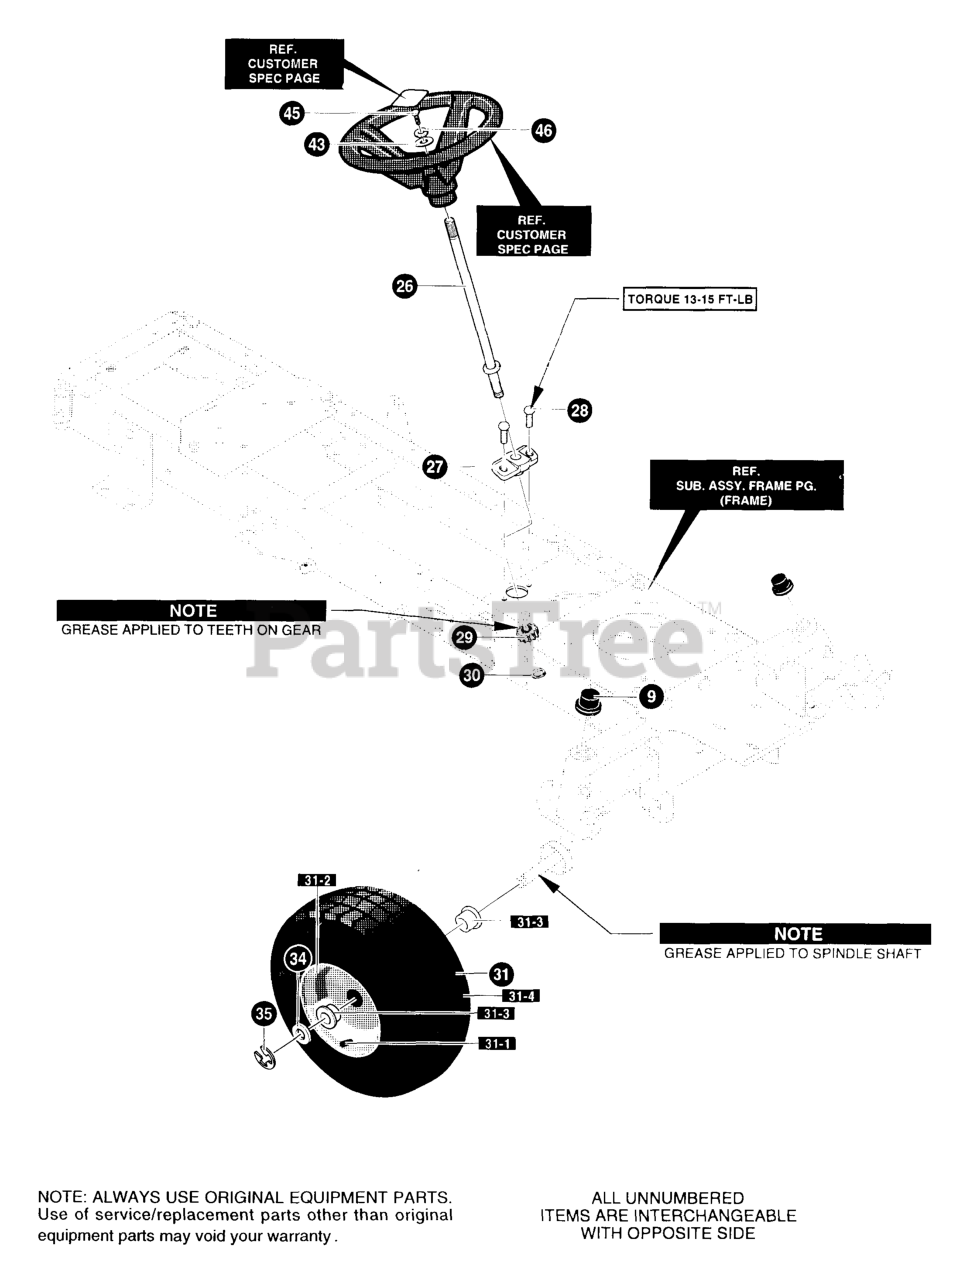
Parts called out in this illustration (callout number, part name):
26	SHAFT, STEERING
27	BEARING-LOWER
28	SCREW, 5/16-18 x.0.50 HHWATAPSGIBP
29	GEAR PINNION
30	RING, RET E.54ID.59SH (11X25)
31	TIRE & RIM 15X6-6
31-1	VALVE STEM
31-2	RIM, CARLISLE
31-3	BEARING
31-4	TIRE, 15X6X6
34	WASHER, FLAT .765 x 1.81 x .059
35	"E" RING .574IDX.050/.750SH (11x3)
43	FLATWASHER .281 Xl.25X.06
45	SCREW, 1/4-20X.
46	WASHER (18X32)
